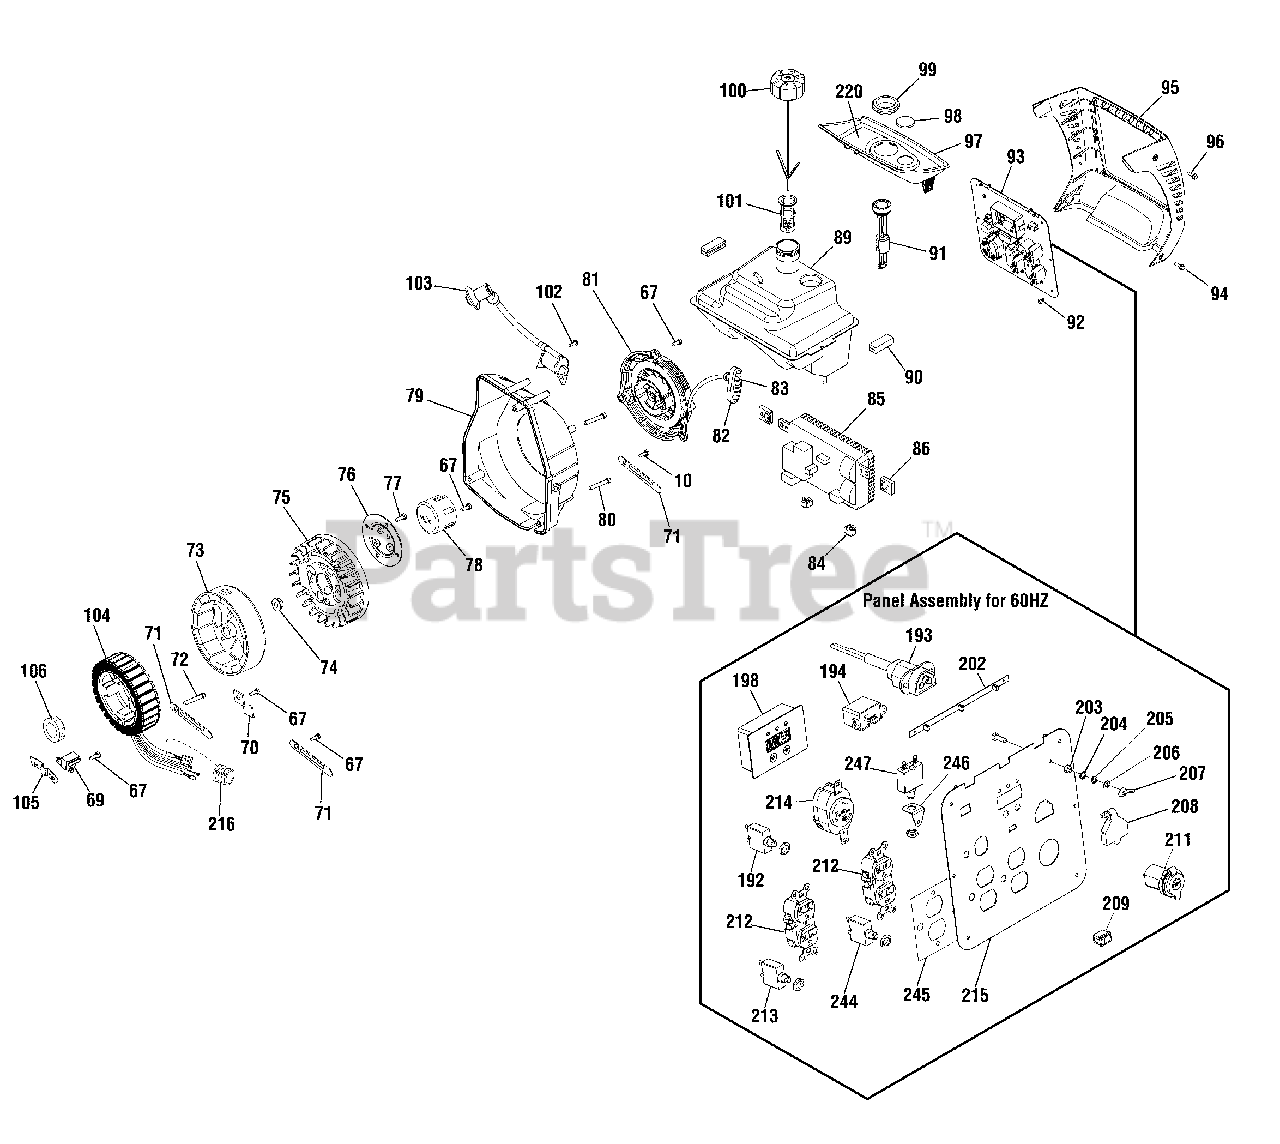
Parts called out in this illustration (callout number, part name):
10	SCREW
67	BOLT-M6 x 12
69	TRIGGER-IGNITION
70	BRACKET
71	BRACKET
72	SCREW-M6 x 60
74	NUT, FLANGE M14
76	TERMINAL
77	BOLT-M6 x 16
79	COVER-FAN
80	BOLT-M6 x 55
81	STARTER-REWIND
82	GRIP
83	INSERT-GRIP
84	MOUNT-VIBRATION
86	MOUNT-VIBRATION
90	MOUNT-VIBRATION
92	SCREW
94	SCREW-M5 x 30
96	SCREW-M6 x 56
101	FILTER-FILLER NECK
102	SCREW
103	COIL-IGNITION
105	BRACKET
106	SEAL-OIL
192	BREAKER-CIRCUIT
193	PORT-PARALLEL
213	BREAKER-CIRCUIT
215	PANEL-CONTROL
216	COVER-RUBBER
244	BREAKER-CIRCUIT
247	BREAKER-CIRCUIT
